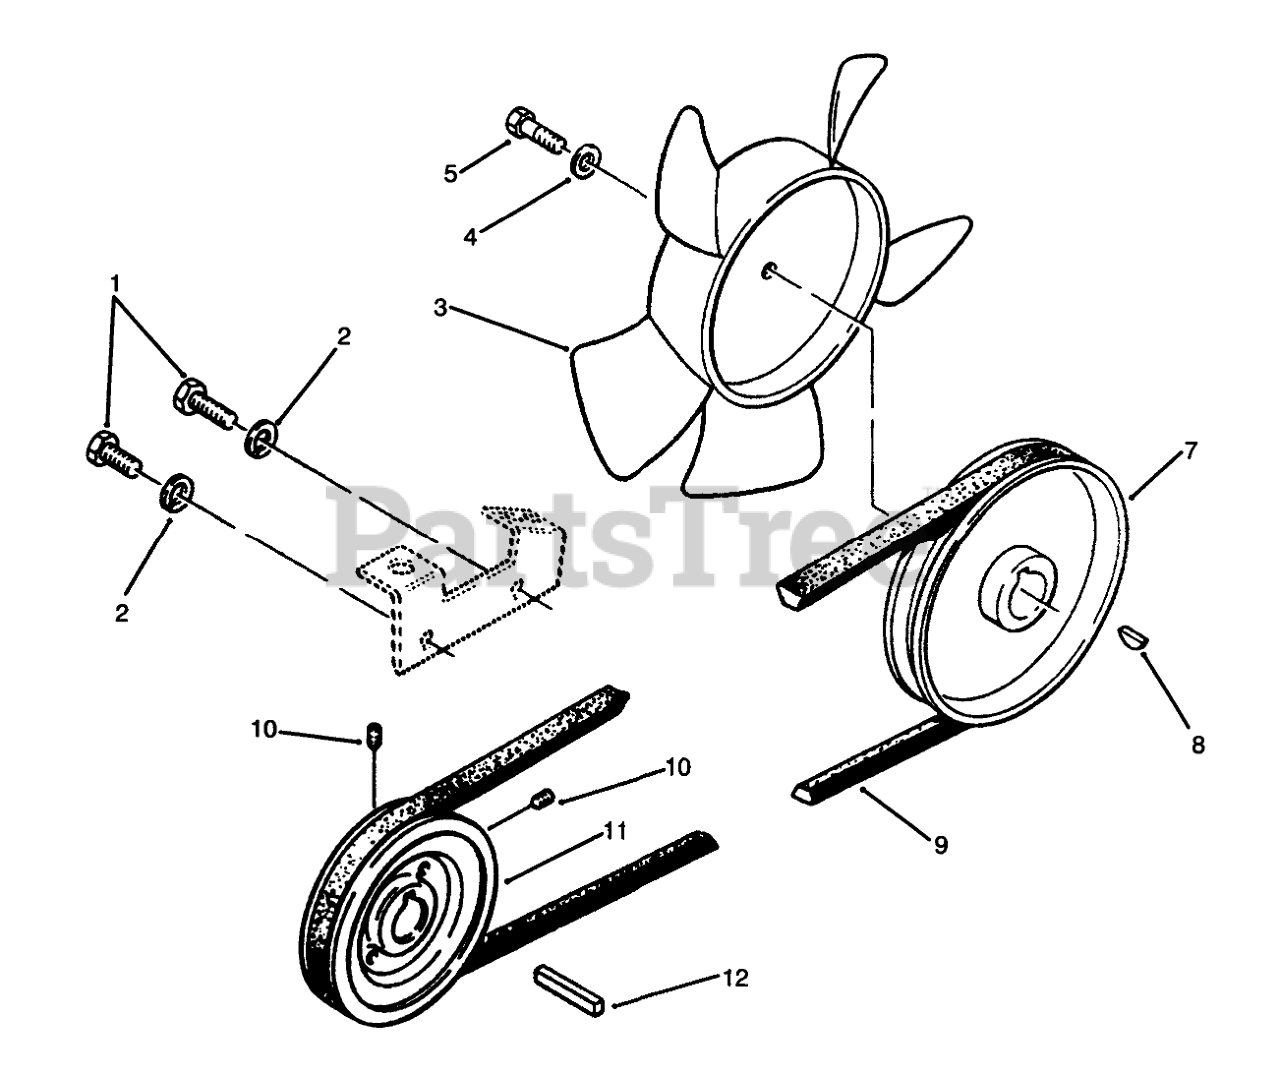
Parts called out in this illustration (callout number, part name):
1	SCREW-HH
2	WASHER-FLAT
3	NYLON FAN-L-CW
4	WASHER
5	SCREW-HH
7	PULLEY
8	KEY-WOODRUFF
9	BELT-V
10	SCREW-SET, HSH
11	PULLEY
